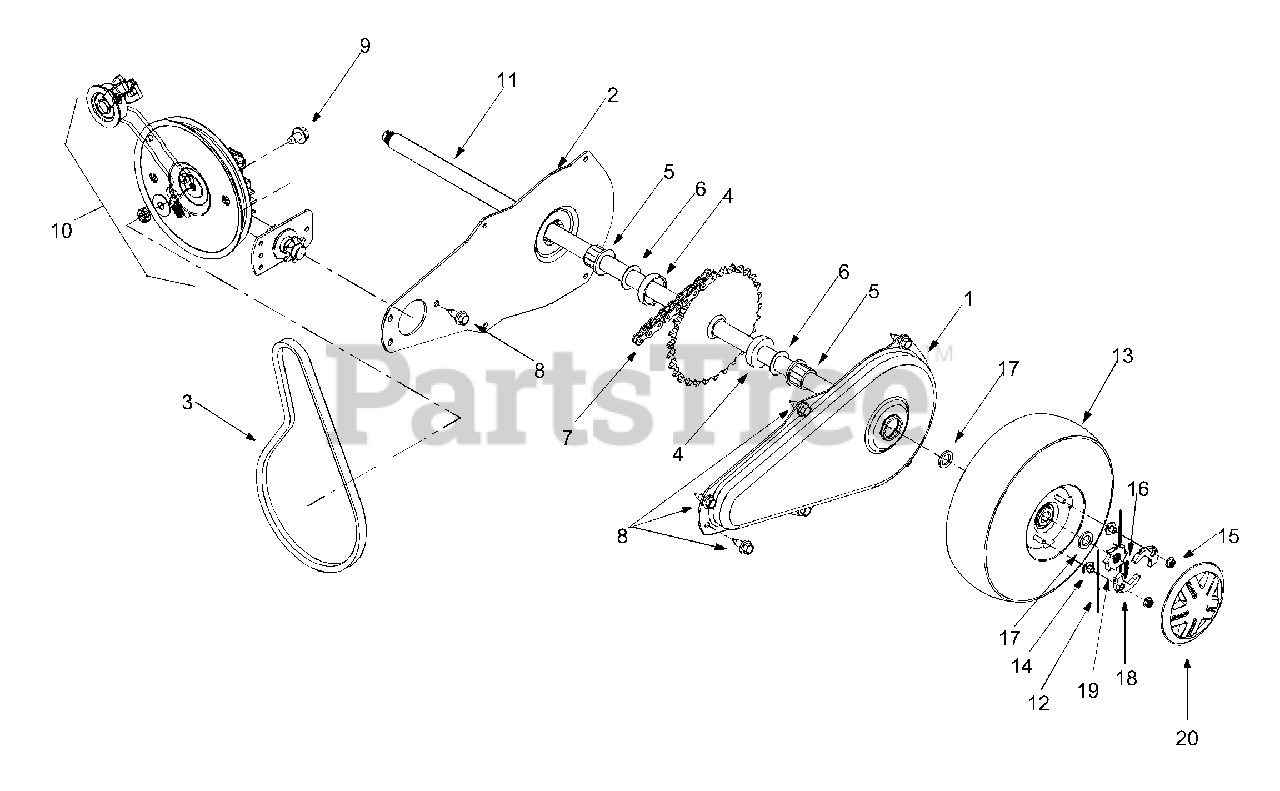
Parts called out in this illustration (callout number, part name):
3	V-Belt
4	Spacer
5	Hex Flange Bearing
6	Flat Washer
7	Chain
8	Hex Washer Screw 1/4-14
9	Hex Washer Screw 5/16
10	Transmission Asm
11	Axle Asm
12	Plastic Spring Ratchet
14	Hex Nut 1/4-20
15	Hex Flanged Lock Nut 1/4-20
16	Cotter Pin
17	Flat Washer 5/8 ID x 1.0 OD
18	Pawl LH .345 ID
19	Wheel Ratchet 1.62 OD x .5 serr
20	Hubcap
